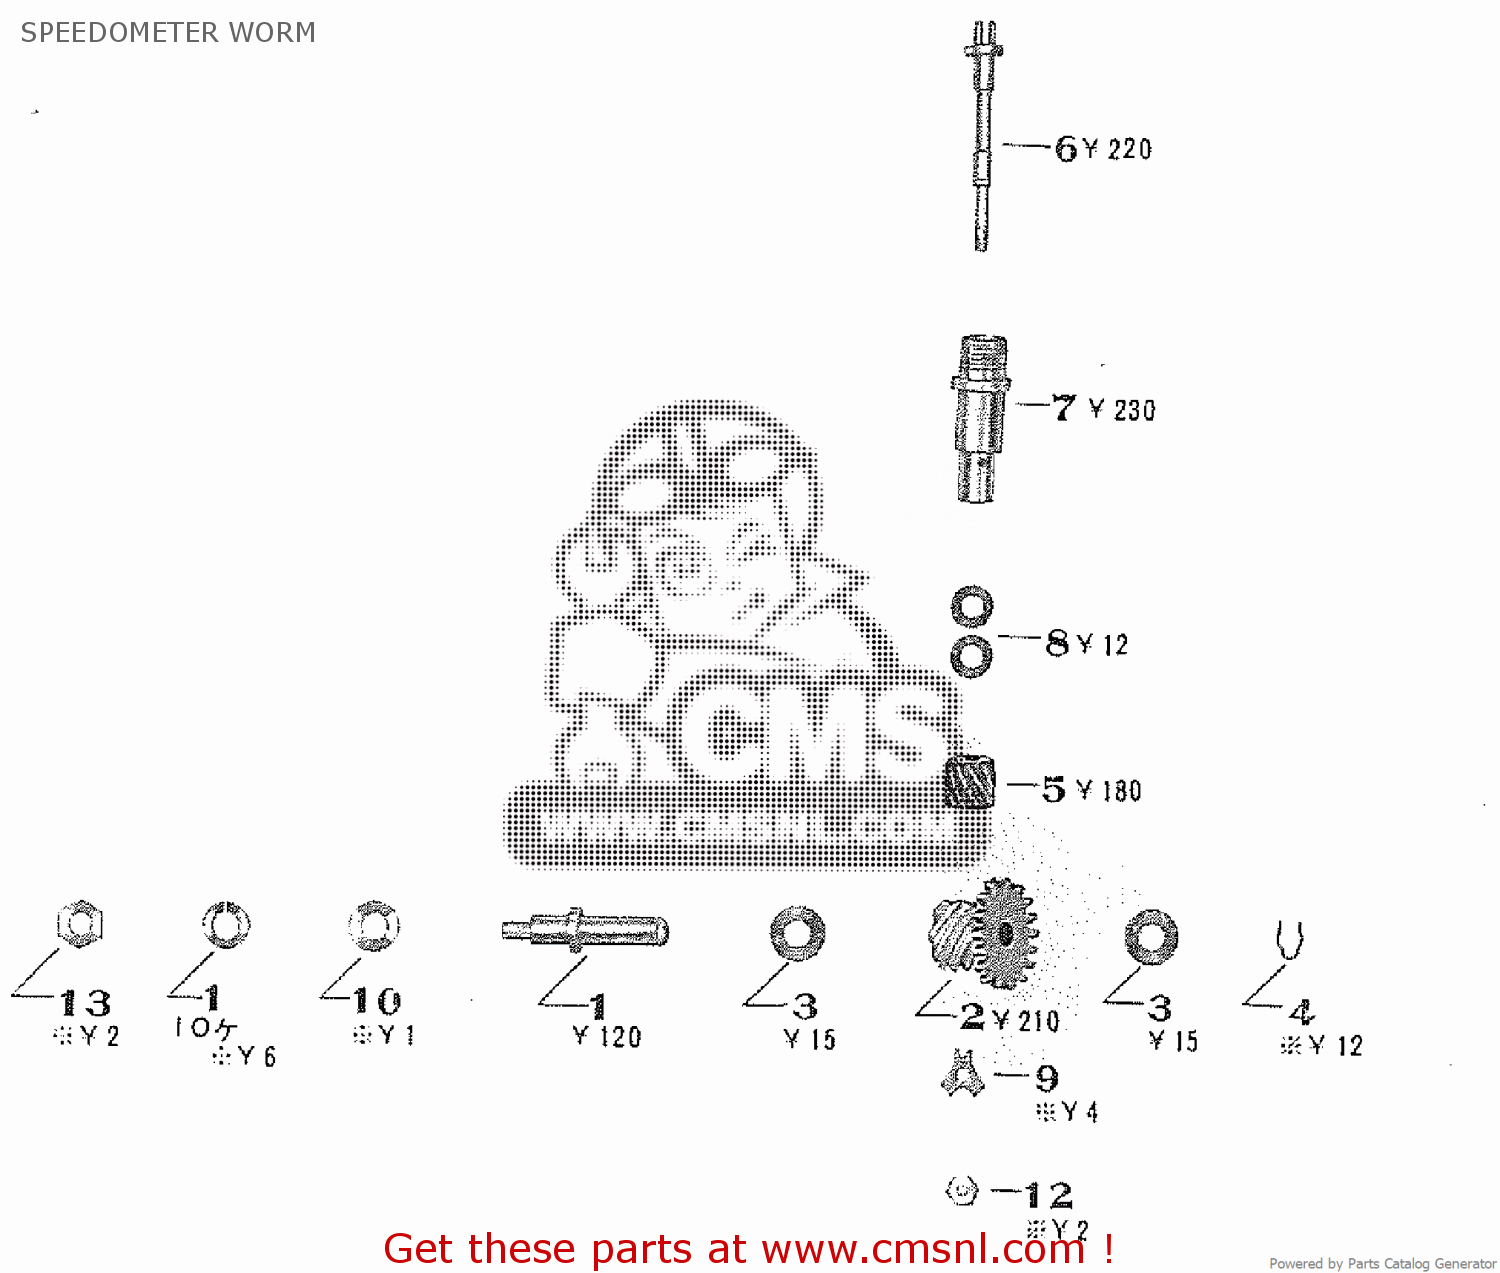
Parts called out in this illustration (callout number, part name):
1	SPEEDOMETER WORM SHAFT
2	SPEEDOMETER WORM
3	WORM THRUST WASHER
4	WORM SET CIRCLIP
5	SPEEDOMETER WORM GEAR
6	WORM GEAR SHAFT
7	WORM GEAR HOLDER
8	WORM GEAR THRUST WASHER
9	WORM GEAR SET WASHER
10	8MM LIGHT PLANE WASHER
12	5MM HEXAGON NUT
13	8MM LIGHT HEXAGON NUT
